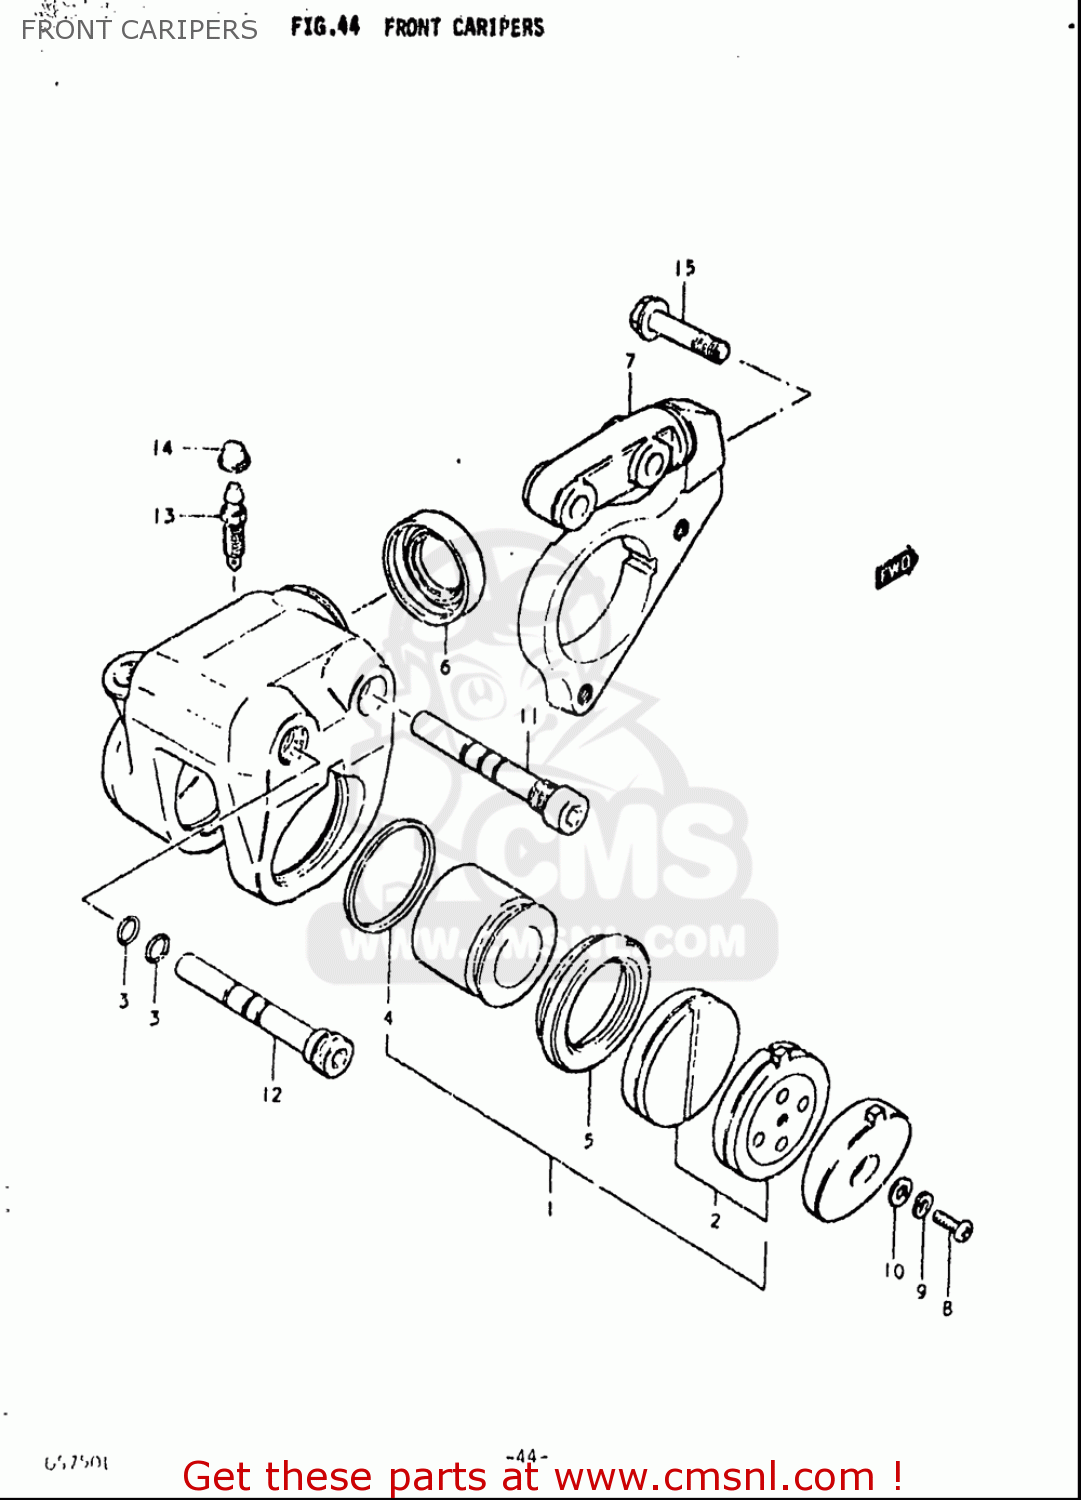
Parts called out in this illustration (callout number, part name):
2	PAD SET (NAS)
3	O RING,AXLE CALIPER
4	SEAL,PISTON
5	BOOT,PISTON
6	BOOT,HOLDER
8	SCREW
9	WASHER,LOCK
10	WASHER
11	AXLE,CALIPER
12	AXLE NO.2
13	BREATHER
14	CAP,BLEEDER PLUG
15	BOLT
